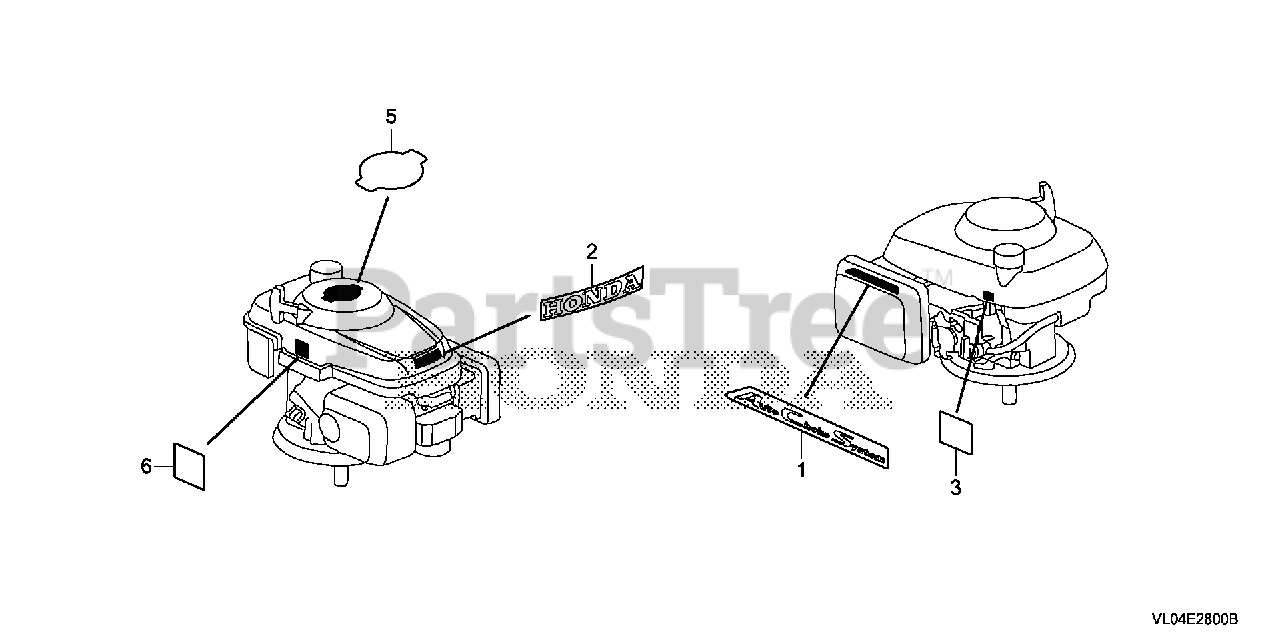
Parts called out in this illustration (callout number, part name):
2	MARK, HONDA (TYPE1) (RED)
3	MARK, FUEL PETCOCK CAUTION
5	MARK, RECOIL COVER
